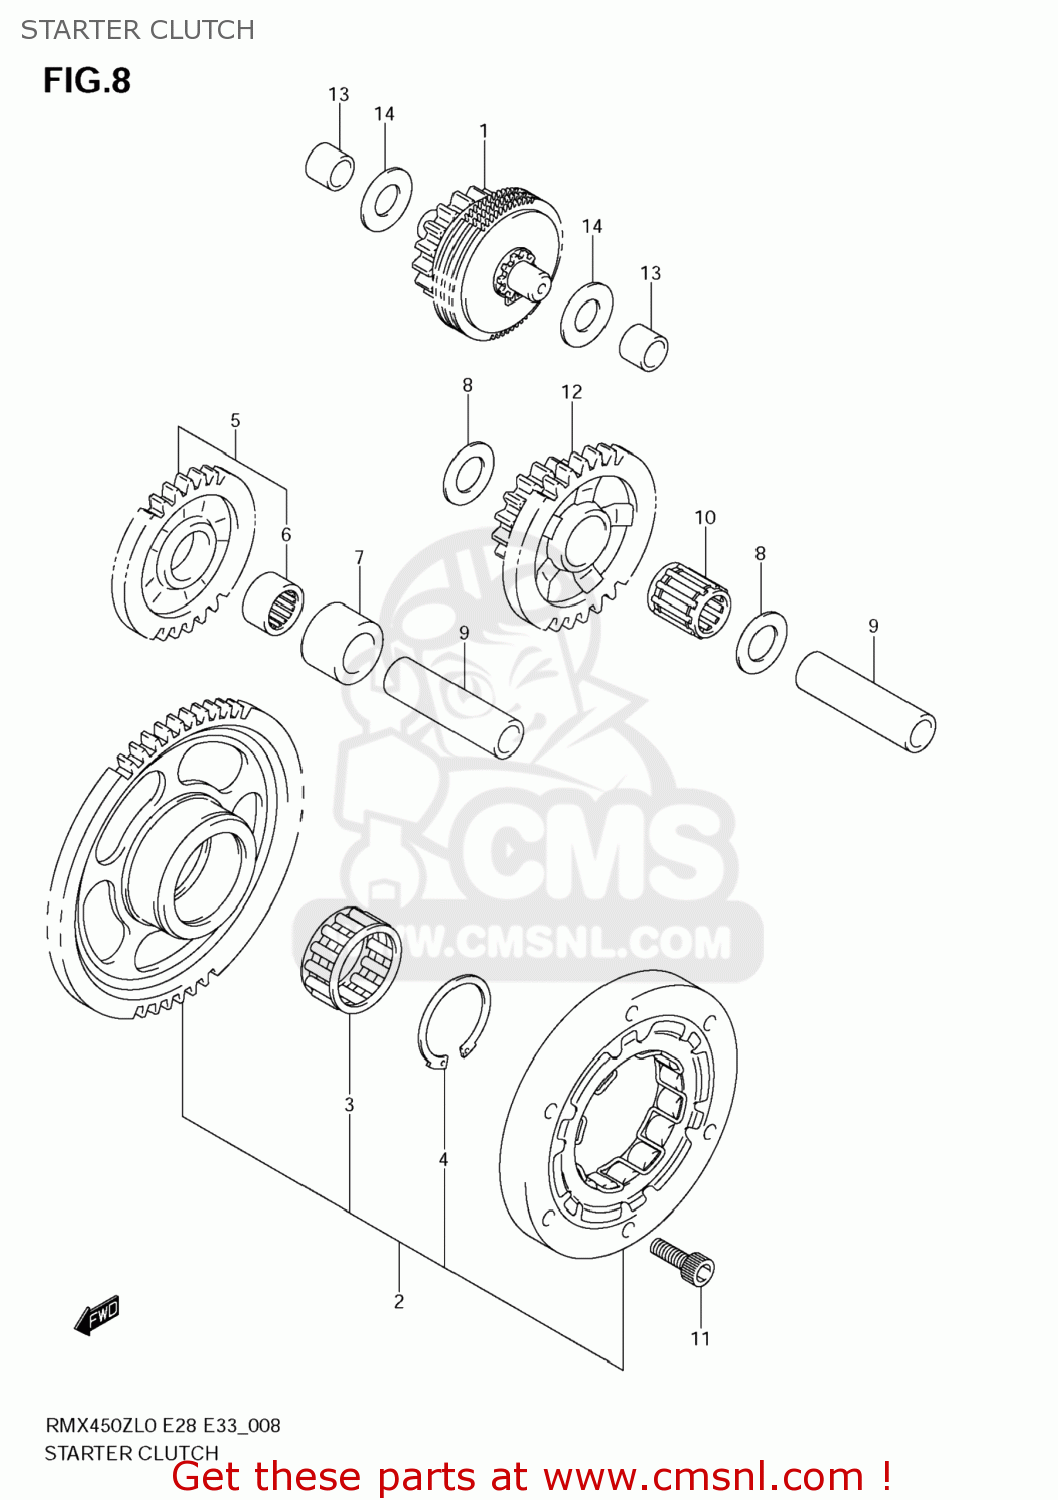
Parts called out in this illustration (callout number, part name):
1	LIMITER ASSY,STARTER IDLE GEAR
2	CLUTCH SET,STARTER
3	BEARING(22X28X14)
4	CIRCLIP
5	GEAR,STARTER IDLE NO.3
6	BEARING(12X16X10)
7	SPACER(12.5X19X13)
8	SHIM(12X20X1)
9	PIN(8X12X45.5)
10	BEARING(12X16X20)
11	BOLT(6X16)
12	GEAR,STARTER IDLE NO.2
13	BUSH,LIMITER GEAR SHAFT
14	WASHER
